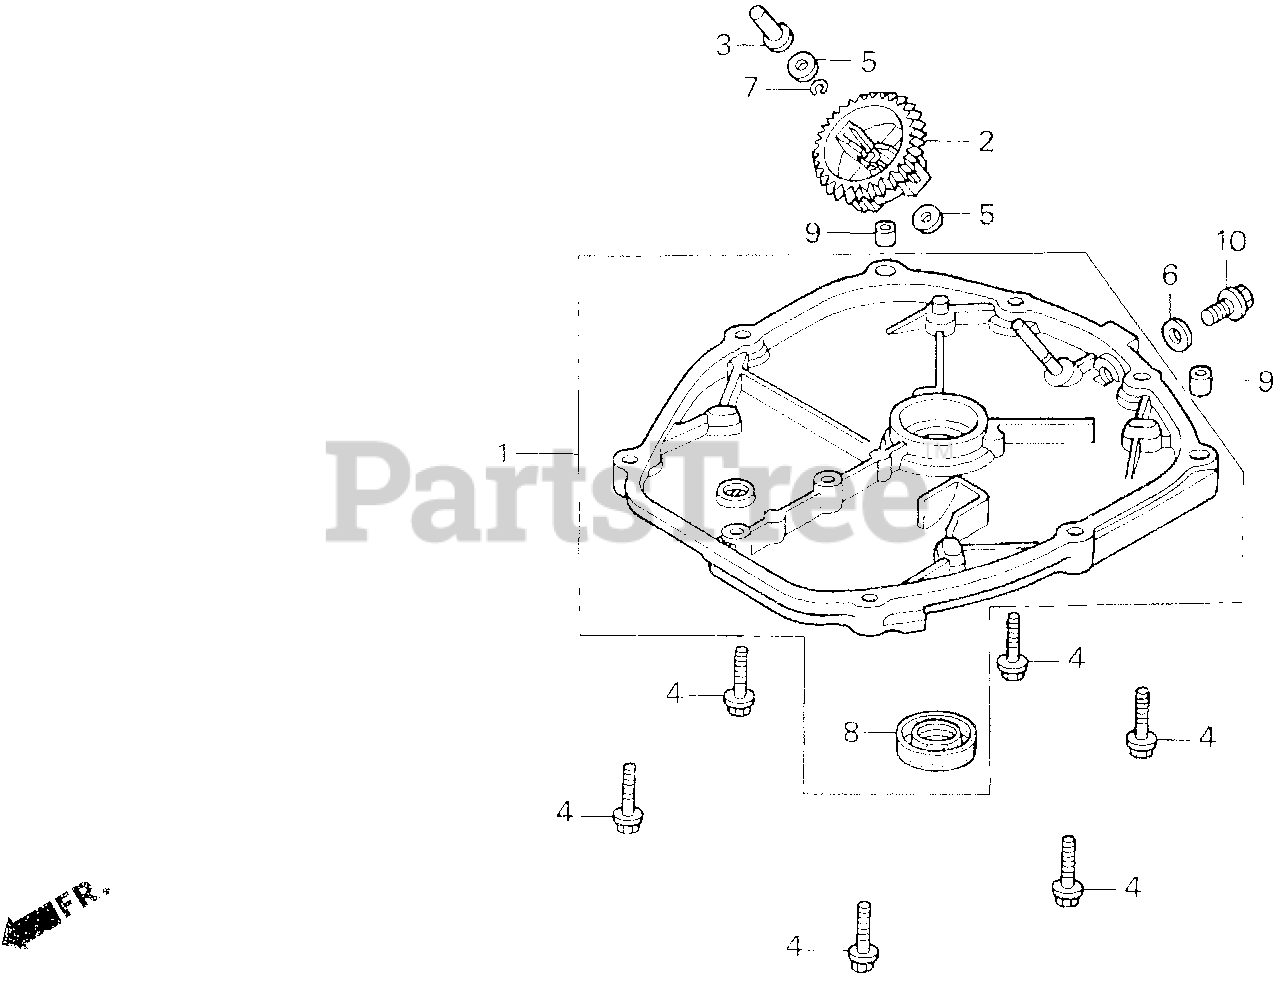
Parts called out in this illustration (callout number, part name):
1	COVER, CRANKCASE SIDE
2	GOVERNOR ASSY.
3	SLIDER, GOVERNOR
4	BOLT, FLANGE (5X23)
5	WASHER (4.2X13)
6	WASHER (8MM)
7	CLIP, GOVERNOR HOLDER
8	OIL SEAL (17X27X5) (KOYO)
9	PIN A, DOWEL (6X10)
10	BOLT, FLANGE (8X12)
